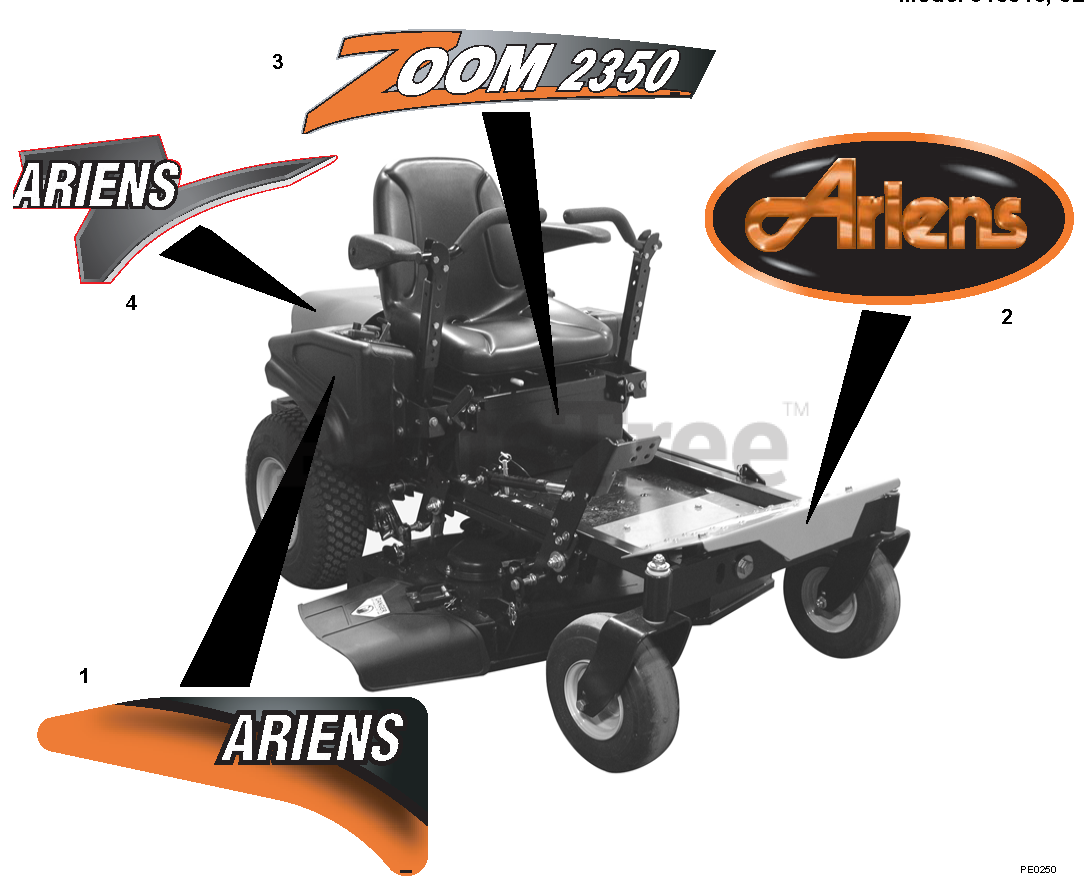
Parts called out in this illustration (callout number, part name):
1	DECAL, RH ARIENS ZOOM TANK
2	DECAL, ARIENS JEWEL (LARGE)
3	DECAL, 1840 ZOOM
4	DECAL,MINI-ZOOM HOOD
